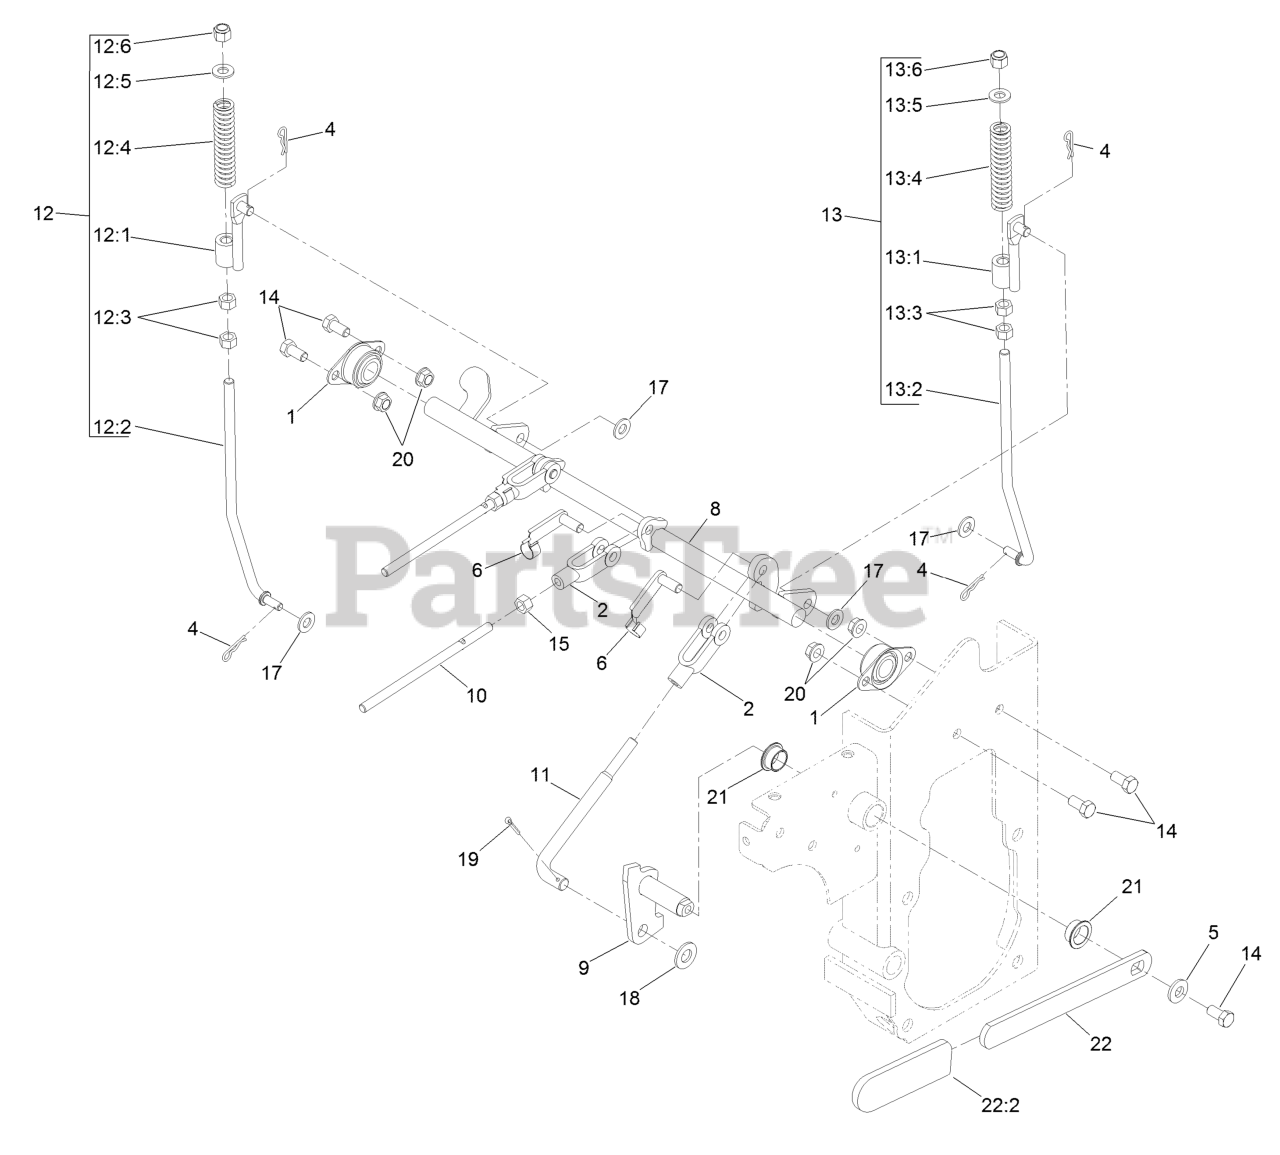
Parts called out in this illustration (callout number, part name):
1	BEARING-FLANGE, SIDE
2	YOKE-LINKAGE, BRAKE
4	PIN-COTTER
5	WASHER-BELLEVILLE
6	PIN-SPRING, CLEVIS
8	SHAFT-BRAKE
9	PIVOT-BRAKE
10	ROD-LINKAGE, BRAKE
11	ROD-LINKAGE, BRAKE
12	RH BRAKE LINKAGE ASM
12:1	BRAKE LINKAGE ASM
12:2	LINK-BRAKE, RH
12:3	NUT-HEX
12:4	SPRING-COMPRESSION
12:5	WASHER-FLAT
12:6	NUT-LOCK
13	LH BRAKE LINKAGE ASM
13:1	BRAKE LINKAGE ASM
13:2	LINK-BRAKE, LH
13:3	NUT-HEX
13:4	SPRING-COMPRESSION
13:5	WASHER-FLAT
13:6	NUT-LOCK
14	SCREW-HH
15	NUT-HEX
17	WASHER-FLAT
18	WASHER-FLAT
19	PIN-COTTER
20	NUT-HHF, WHIZ
21	BUSHING-BRONZE
22	PARK BRAKE HANDLE ASM
22:2	GRIP-LEVER
